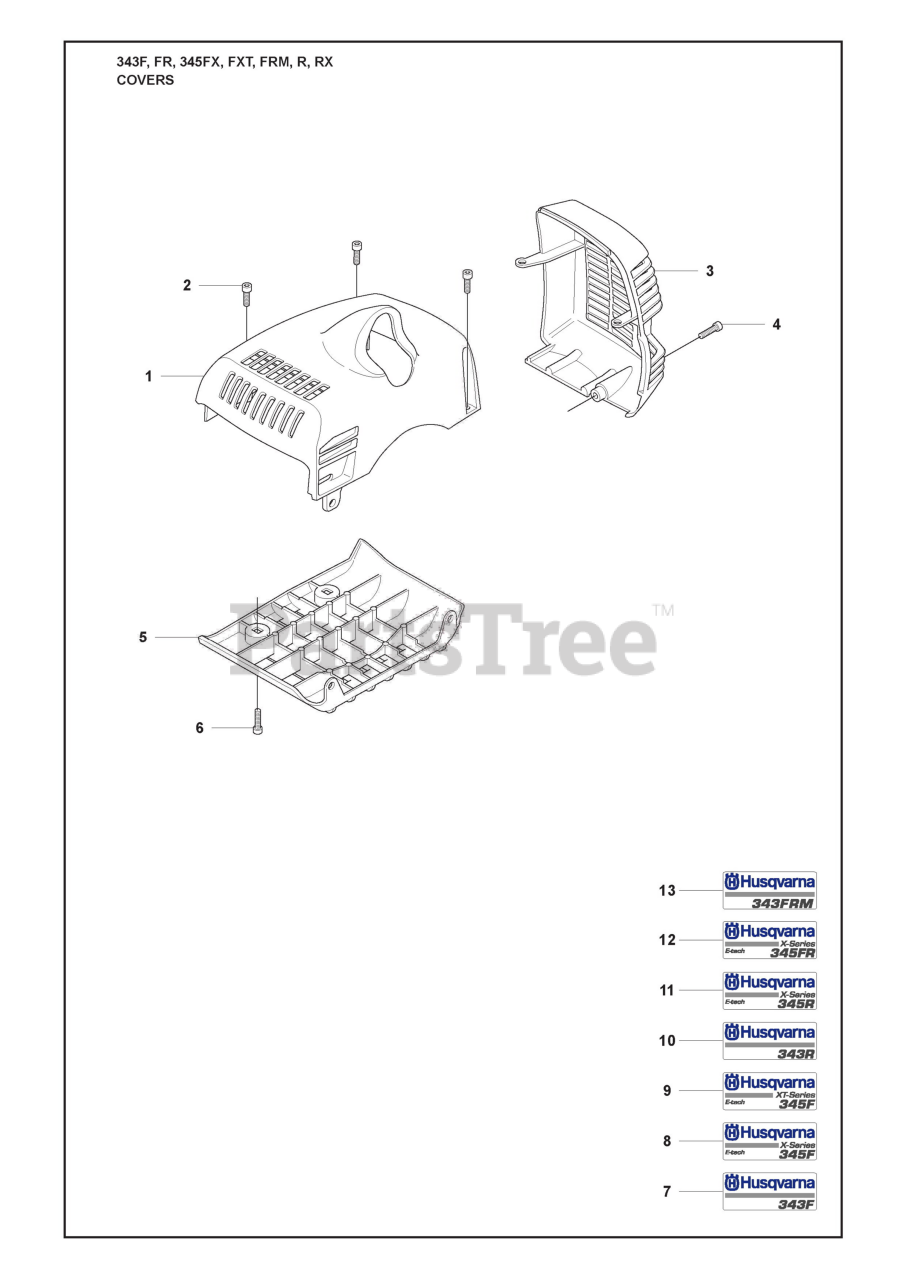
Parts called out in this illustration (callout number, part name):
1	CYLINDER COVER
2	SCREW IHSCFM
3	MUFFLER COVER
4	SCREW IHSCFM
6	SCREW IHSCFM
7	LABEL
8	DECAL
9	DECAL
10	DECAL
11	DECAL
12	LABEL
